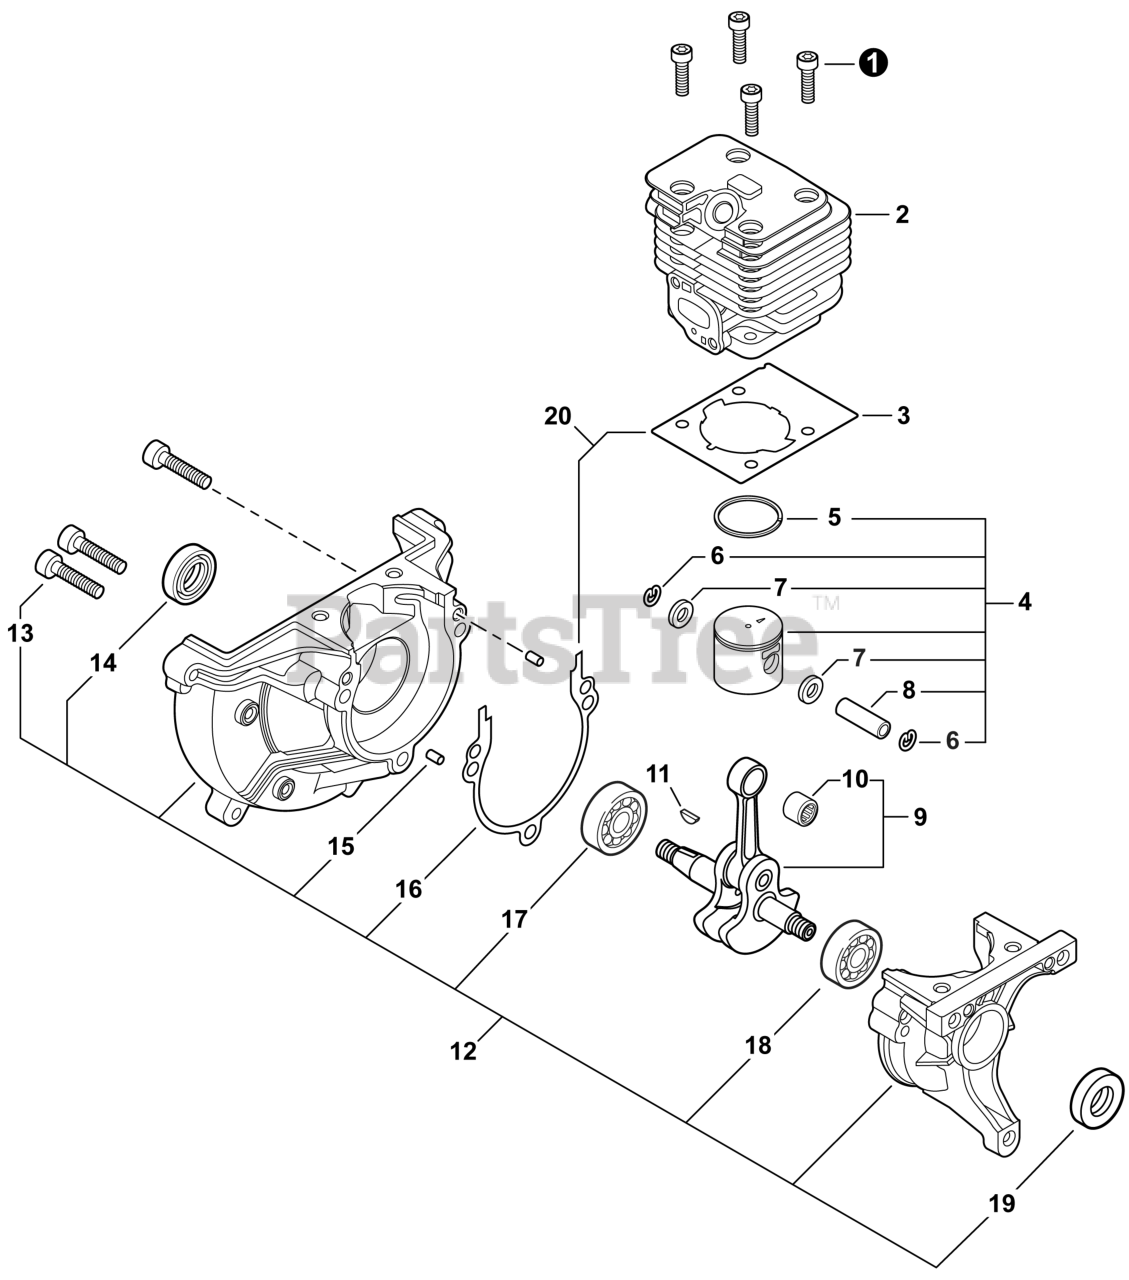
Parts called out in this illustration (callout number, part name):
1	BOLT, TORX 5×20
2	CYLINDER
3	GASKET, CYLINDER
4	PISTON KIT
5	RING, PISTON
6	RING, SNAP
7	WASHER, THRUST
8	PIN, PISTON
9	CRANKSHAFT ASSY
10	BEARING, NEEDLE 9
11	KEY, WOODRUFF
12	CRANKCASE ASSY
13	BOLT, TORX 5×25
14	SEAL, OIL 12
15	PIN, LOCATING 4×8
16	GASKET, CRANKCASE
17	BEARING, BALL 6001
18	BEARING, BALL
19	SEAL, OIL
20	GASKET KIT
